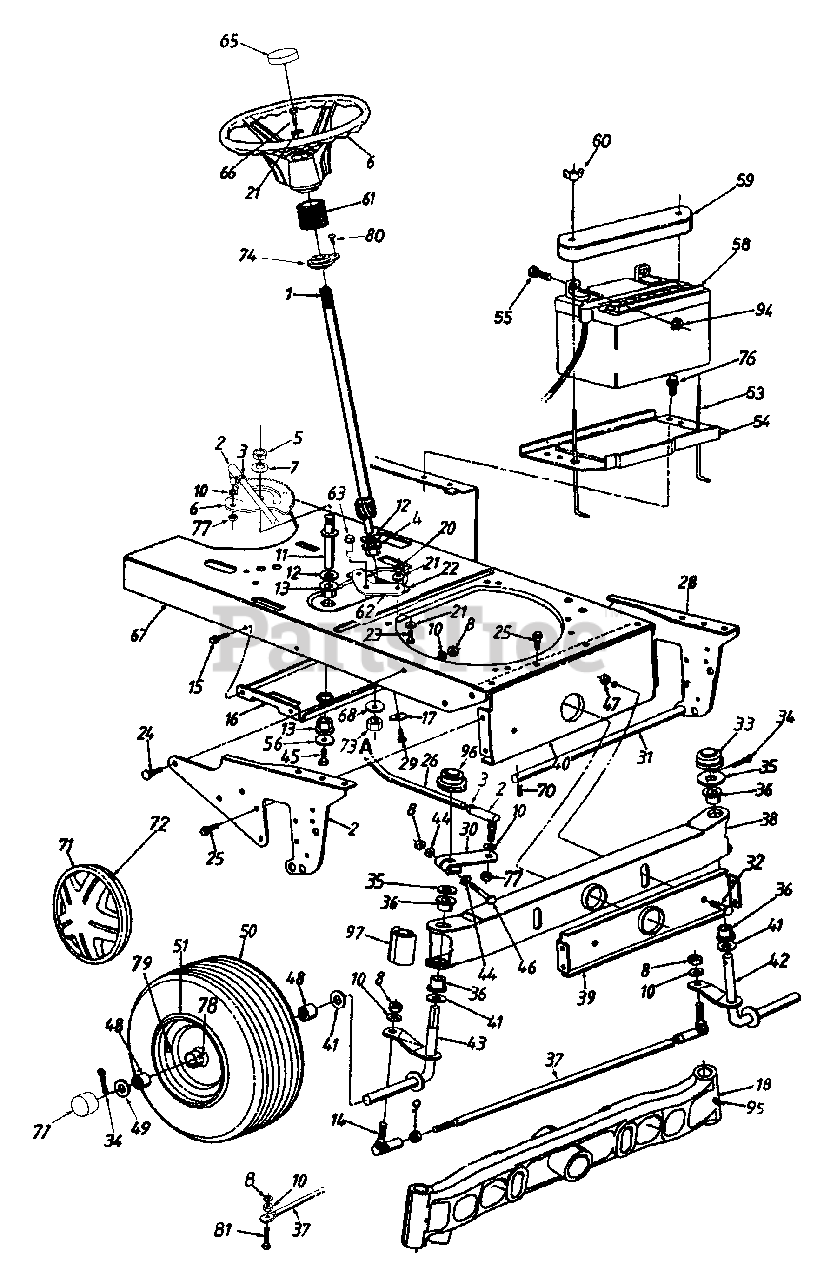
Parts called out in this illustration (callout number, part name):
1	Steering Shaft Ass'y.
2	Ball Joint 7/16-20 Thd.
3	Hex Jam Nut 7/16-20 Thd.
4	Hex Flange Brg.
5	Hex Jam Nut 5/8-18 Thd.
6	Steering Gear Segment
7	Bell-Wash. 5/8" I.D. x 1.25" O.D.
8	Hex Nut 3/8-24 Thd.
9	Hex Jam Nut 3/8-24 Thd.
10	L-Wash. 3/8" I.D.
11	Steering Gear Segment Shaft
12	Fl-Wash. .64" I.D. x 1.24" O.D.
13	Hex Flange Brg. .63" I.D.
14	Ball Joint Ass'y.
15	Hx Wash. Hd. TT-Tap Scr. 1/4-20 x .5" Lg.
17	Cap
18	Pivot Bar Ass'y. (Cast Iron)
20	Hex Nut 5/16-24 Thd.
21	Bell-Wash. .345" I.D. x .88" O.D.
24	Ribbed Neck Bolt 3/8-24 x .8" Lg.
25	Hex Wash. TT-Tap Scr. 5/16-18 x .62" Lg.
26	Steering Drag Link
31	Deck Connecting Rod
32	Shld. Bolt .498" Dia. x 2.45" Lg.
33	Cap
34	Cotter Pin 5/32" Dia.
35	Flat Washer
36	Flange Brg. .757" I.D.
37	Tie Rod (Adjustable)
41	Fl-Wash. .76" I.D. x 1.49" O.D.
42	Front Axle Ass'y. - L.H.
43	Front Axle Ass'y. - R.H.
44	Flat Washer
45	Hex L-Scr. 5/16-18 x .62" Lg.
46	Hex Bolt 3/8-24 x 2.50" Lg.
47	Hex L-Nut 3/8-16 Thd.
48	Flange Brg. .75" I.D.
49	Fl-Wash. .71" I.D. x 1.5" O.D.
56	Fl-Wash. .33" I.D. x 1.25" O.D.
58	Battery
59	Battery Cover
60	Wing Nut Plastic 1/4-20 Thd.
61	Steering Bellow (Style 0, 3, 5, 9)
65	Steering Cap (Round)
66	Hex L-Bolt 5/16-18 x 1" Lg.
70	Internal Cotter Pin
71	Hub Cap
72	Spring Clip
73	Hex Nut 3/8-16 Thd.
74	Flange Bearing (Style A)
76	Hex Wash. B-Tap Scr. 1/4 x .62" Lg.
77	Hex Jam L-Nut 3/8-24 Thd.
78	Grease Fitting
79	Air Valve
80	Oval Hd. Cr. - Sunk Scr. #10 x 5/8" Lg. (Style A)
81	Hex Bolt 3/8-24 x 1.5" Lg. (Gr. 5)
94	Hex L-Nut 1/4-20 Thd.
95	Grease Fitting
97	End Cap w/Fitting
